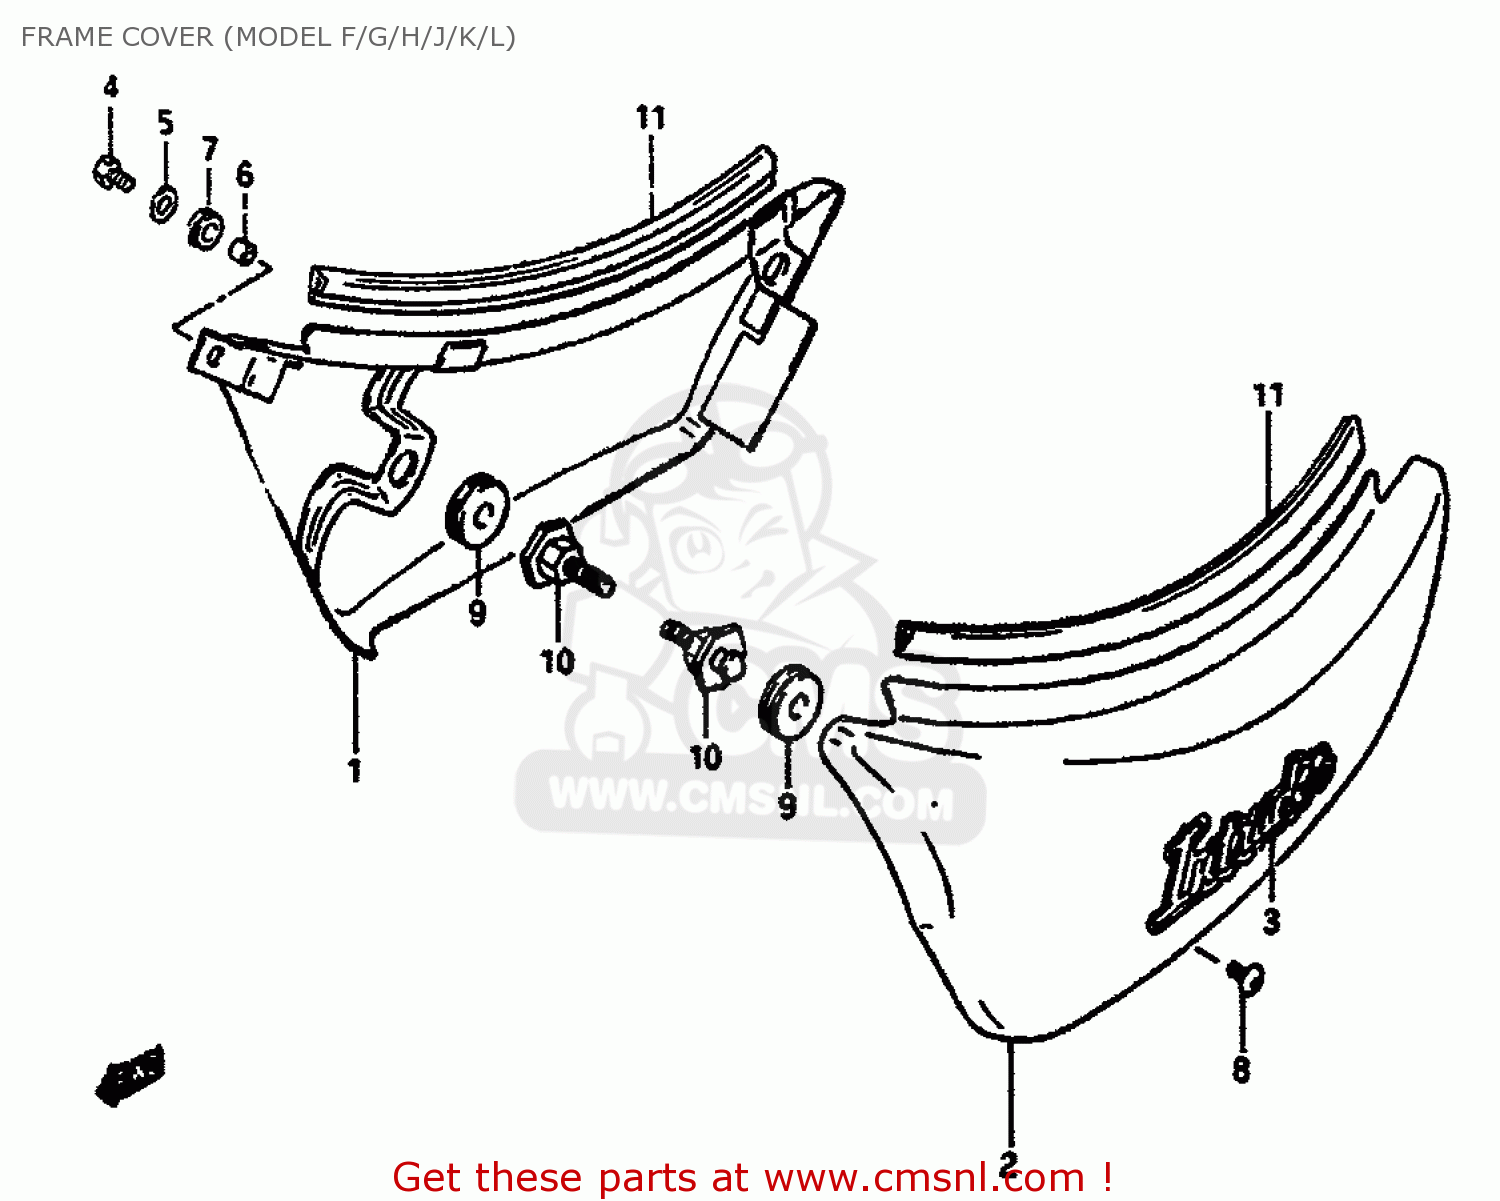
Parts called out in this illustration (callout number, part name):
1	COVER,FRAME,RIGHT
2	COVER,FRAME,LEFT
3	EMBLEM,FRAME COVER
4	BOLT
5	WASHER(6.5X18X1.6)
6	SPACER (6.1X8X5.2)
7	CUSHION
8	SCREW
9	CUSHION
10	BOSS,FRAME COVER
11	MOLDING, FRAME COVER
